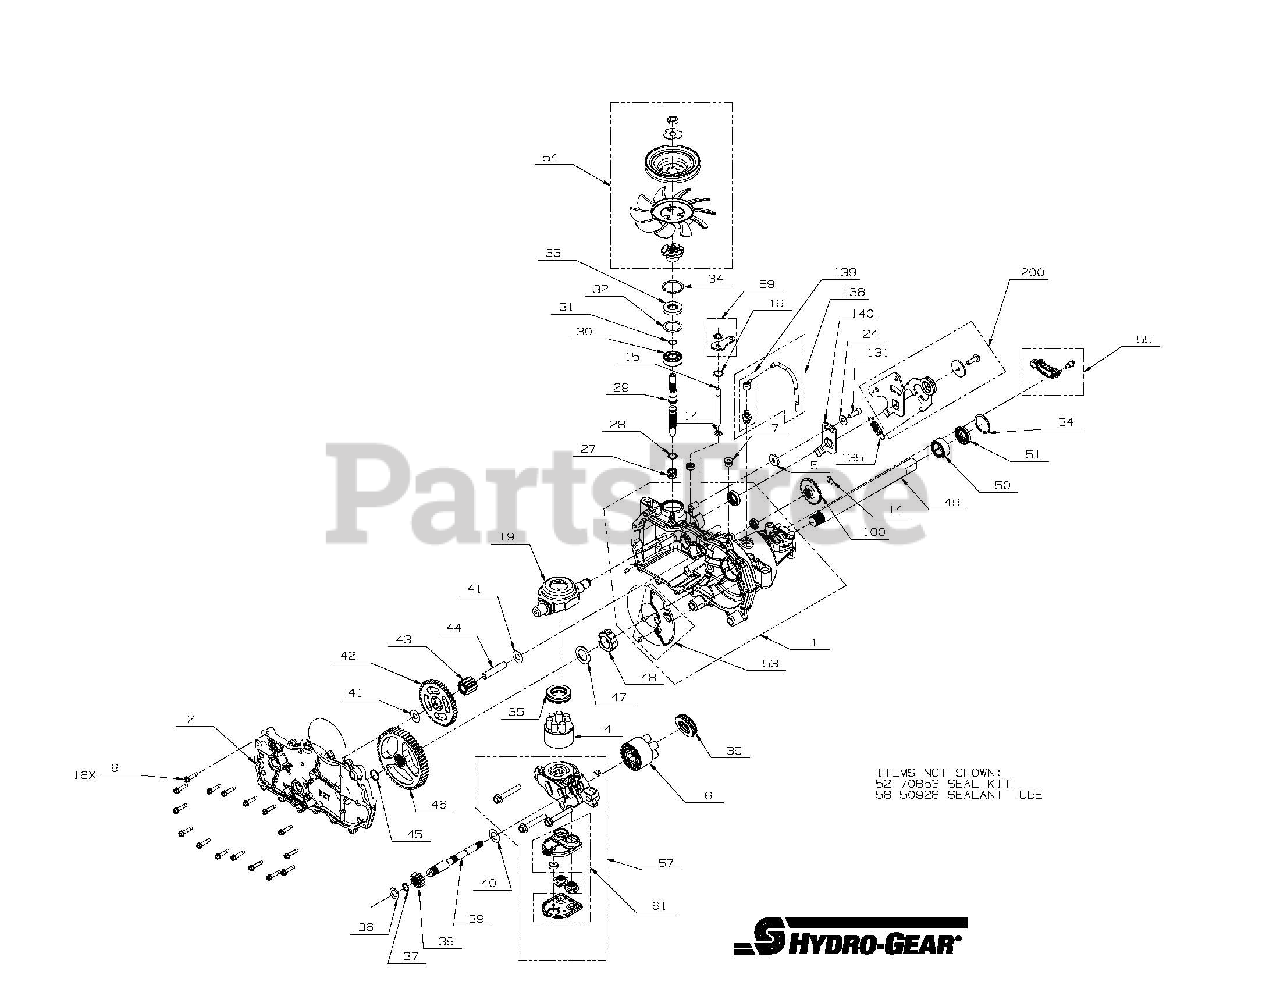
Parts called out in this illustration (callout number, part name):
1	ASSEMBLY, MAIN HOUSING
2	ASSEMBLY, SIDE HOUSING
4	ASSY, BLOCK 7 PISTON
5	SPACER
6	KIT, 10 CC BLOCK
7	Gravely N/A
9	SCREW,HEX WASHER 1/4-20X1.125
14	RING. RETAINING
15	ROD, BYPASS
16	RING, RET .750
19	TRUNNION, SWASHPLATE
24	WASHER
27	SPRING. BLOCK
28	WASHER. THRUST .59 X .79 X .04
29	SHAFT, INPUT
30	BRG, BALL 17X40X12
31	RING, RET WIRE .561 ID
32	WASHER 1.23X1.56X.04
33	SEAL, LIP 17X40X7
34	RING, RET 1.56 INT
35	BEARING. THRUST 30 X 52 X 13
36	WASHER .63X1.0X.05
37	RING, RET 62 EXT
38	GEAR, 13T PINNION
39	SHAFT, MOTOR
40	WASHER .71 X 1.16 X .04
41	WASHER .5X1.0X.032
42	GEAR, 10T/48T
43	GEAR, 10T JACKSHAFT
44	JACK SHAFT (PIN)
45	Gravely N/A
46	Gravely N/A
47	Gravely N/A
48	Gravely N/A
49	Gravely N/A
50	Gravely N/A
51	Gravely N/A
52	KIT, SEALS AND RETAINING
53	KIT, EXPANSION PLATE RH
54	FAN PULLEY KIT 4.5X1.625
55	BRAKE ARM-LH, EZT
57	Gravely N/A
58	SEALANT TUBE 10.1OZ.
59	KIT, BYPASS ARM
61	KIT, FILTER
100	DISC, COG BRAKE
131	SHCS 5/16-24X1 PATCH
135	SPRING, HYDROGEAR P/N 51833
138	Gravely N/A
139	Gravely N/A
140	ARM, NEUTRAL RIGHT
200	Gravely N/A
